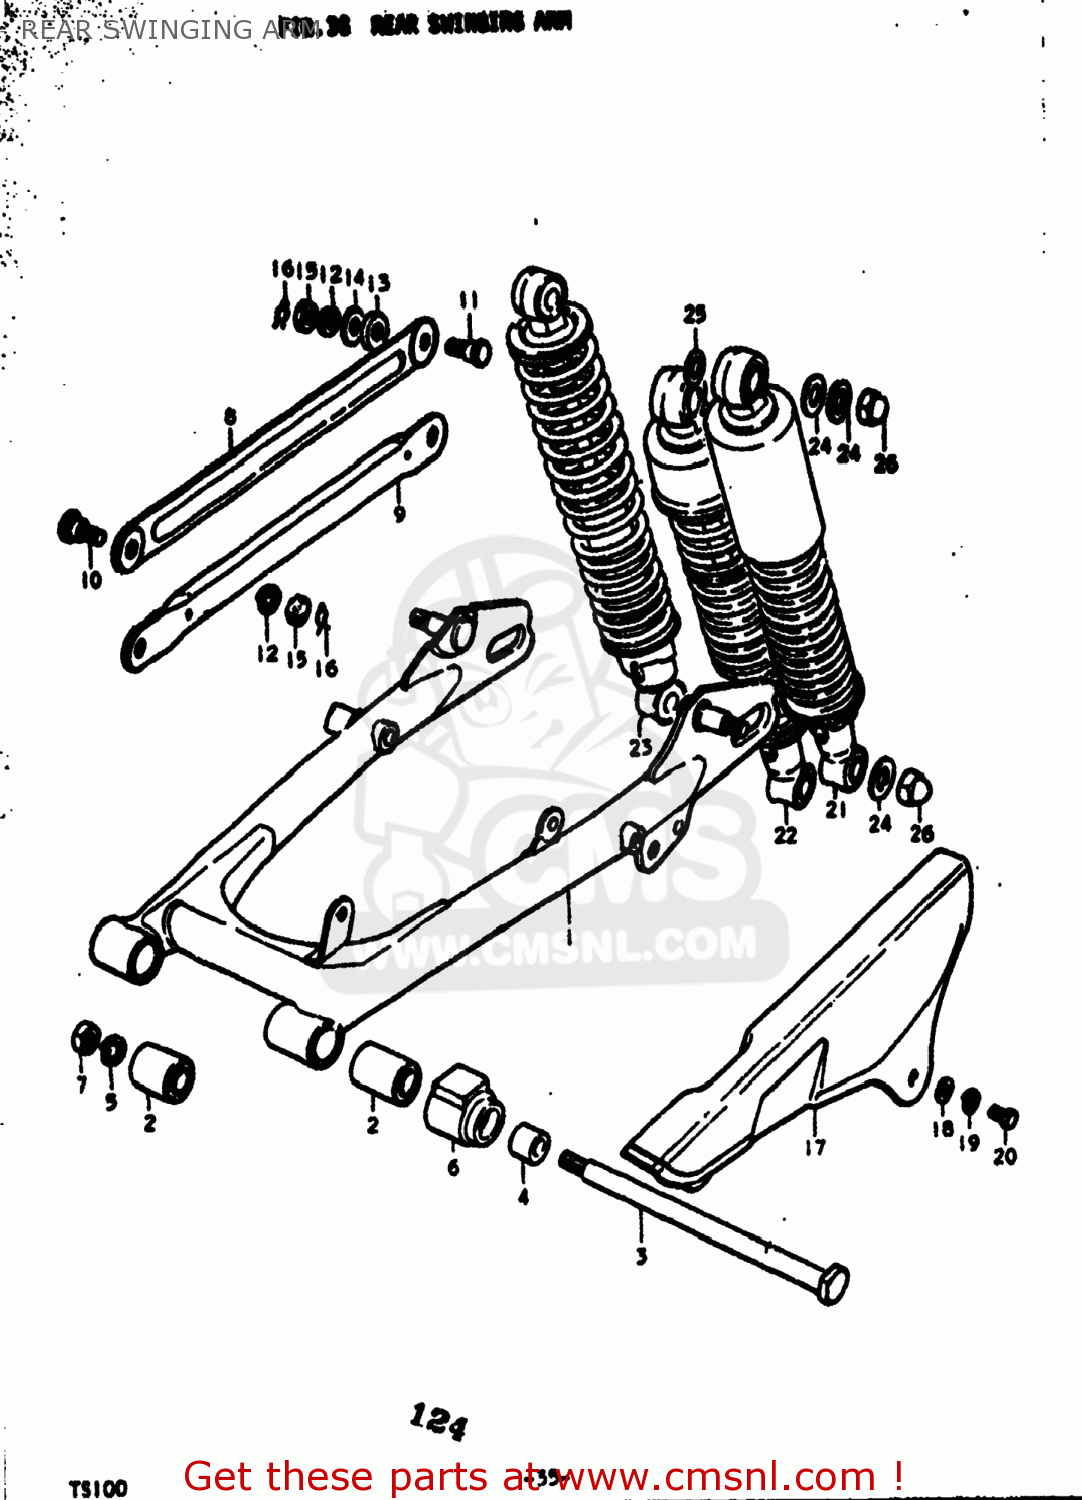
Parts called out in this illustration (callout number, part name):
1	SWING ARM ASSEMBLY,REAR
2	BUSHING(10X23X35)
3	SHAFT, PIVOT
4	SPACER
5	LOCK WASHER
6	BUFFER,CHAIN TOUCH DEFLECTOR
7	NUT
8	TORQUE LINK,REAR
9	TORQUE LINK, REAR
10	BOLT(8X22.5)
11	BOLT
12	LOCK WASHER
13	WASHER
14	WASHER
15	NUT
16	CLIP
17	CASE,CHAIN
18	WASHER
19	LOCK WASHER
20	BOLT(6X8)
21	ABSORBER ASSEMBLY,REAR SHOCK
22	ABSORBER ASSEMBLY,REAR SHOCK
23	ABSORBER ASSEMBLY,REAR SHOCK
24	WASHER
25	WASHER
26	NUT
